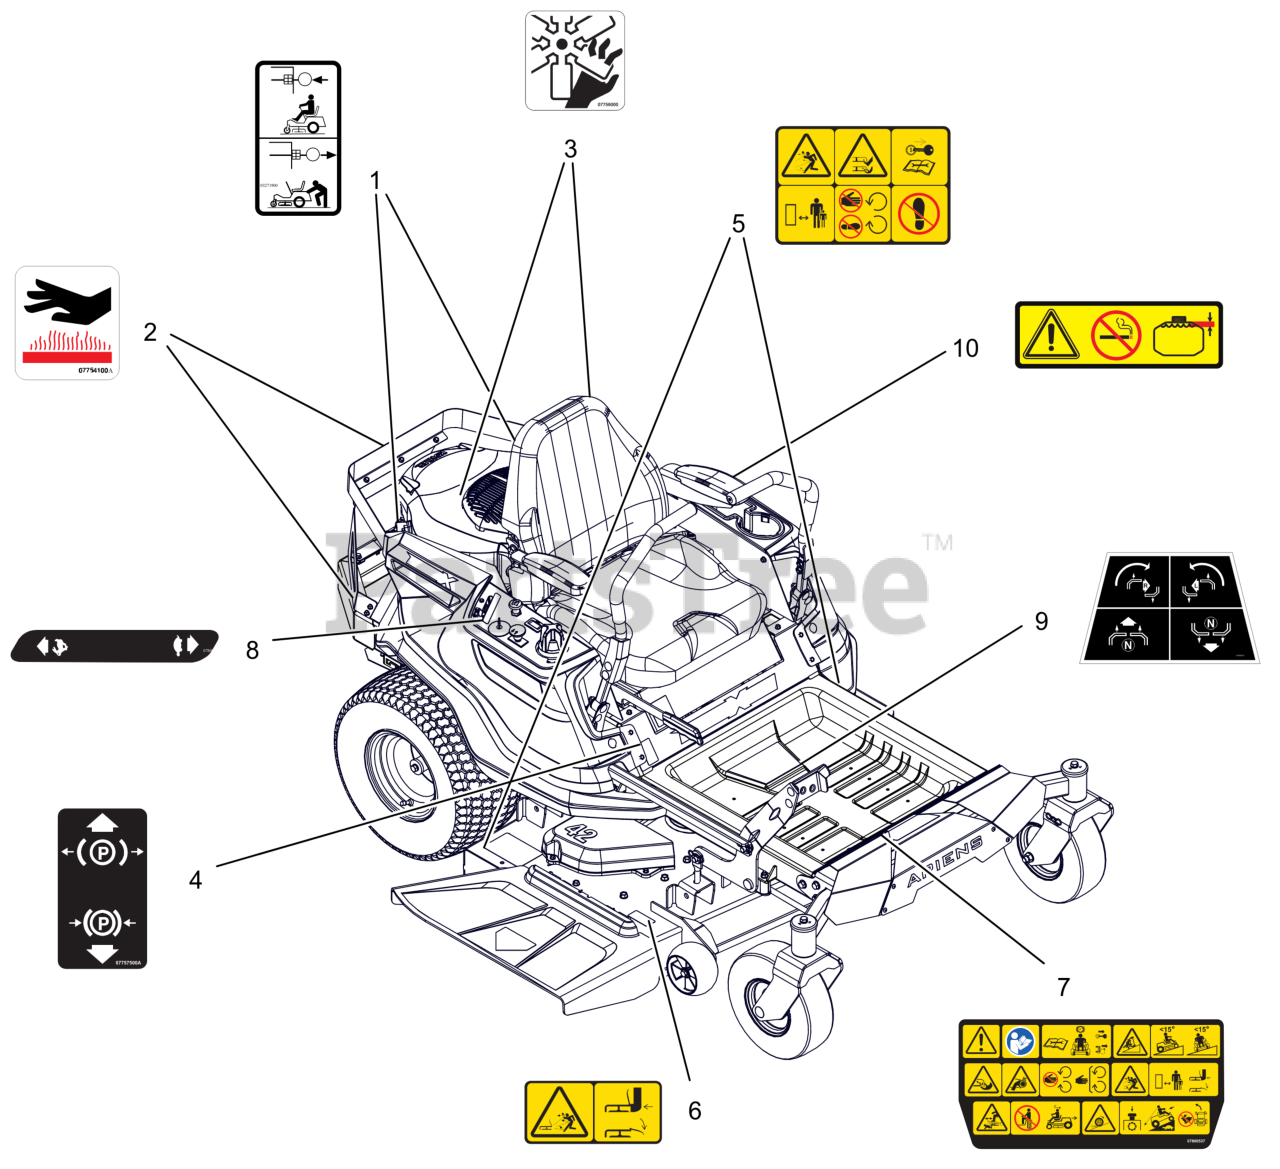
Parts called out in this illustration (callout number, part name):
1	DECAL, TRANSMISSION DISCONNECT
2	DECAL, HOT SURFACE
3	DECAL, DANGER FAN
4	DECAL, PARKING BRAKE LEVER
5	DECAL, SAFETY - MOWER DECK
6	DECAL, SAFETY - DECK GUARDING
7	DECAL, MAIN SAFETY
8	DECAL, DASH DECAL
9	DECAL, STEERING
10	DECAL, FUEL WARNING
